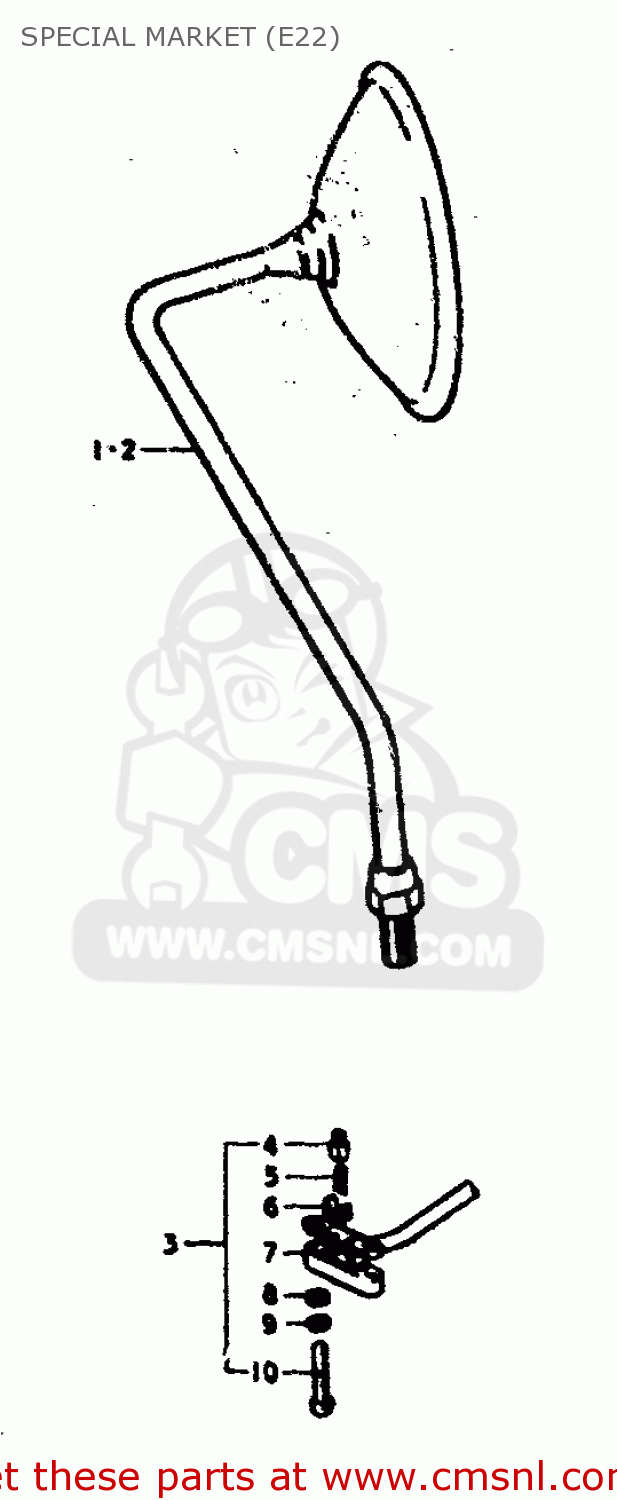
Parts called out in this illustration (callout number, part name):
1	MIRROR ASSEMBLY,RIGHT
2	MIRROR ASSEMBLY,LEFT
3	SWITCH ASSY,STOP
4	HOLDER
5	SPRING
6	PLATE
7	COVER,FR BK TERMINAL BASE
8	WASHER
9	LOCK WASHER
10	SCREW
